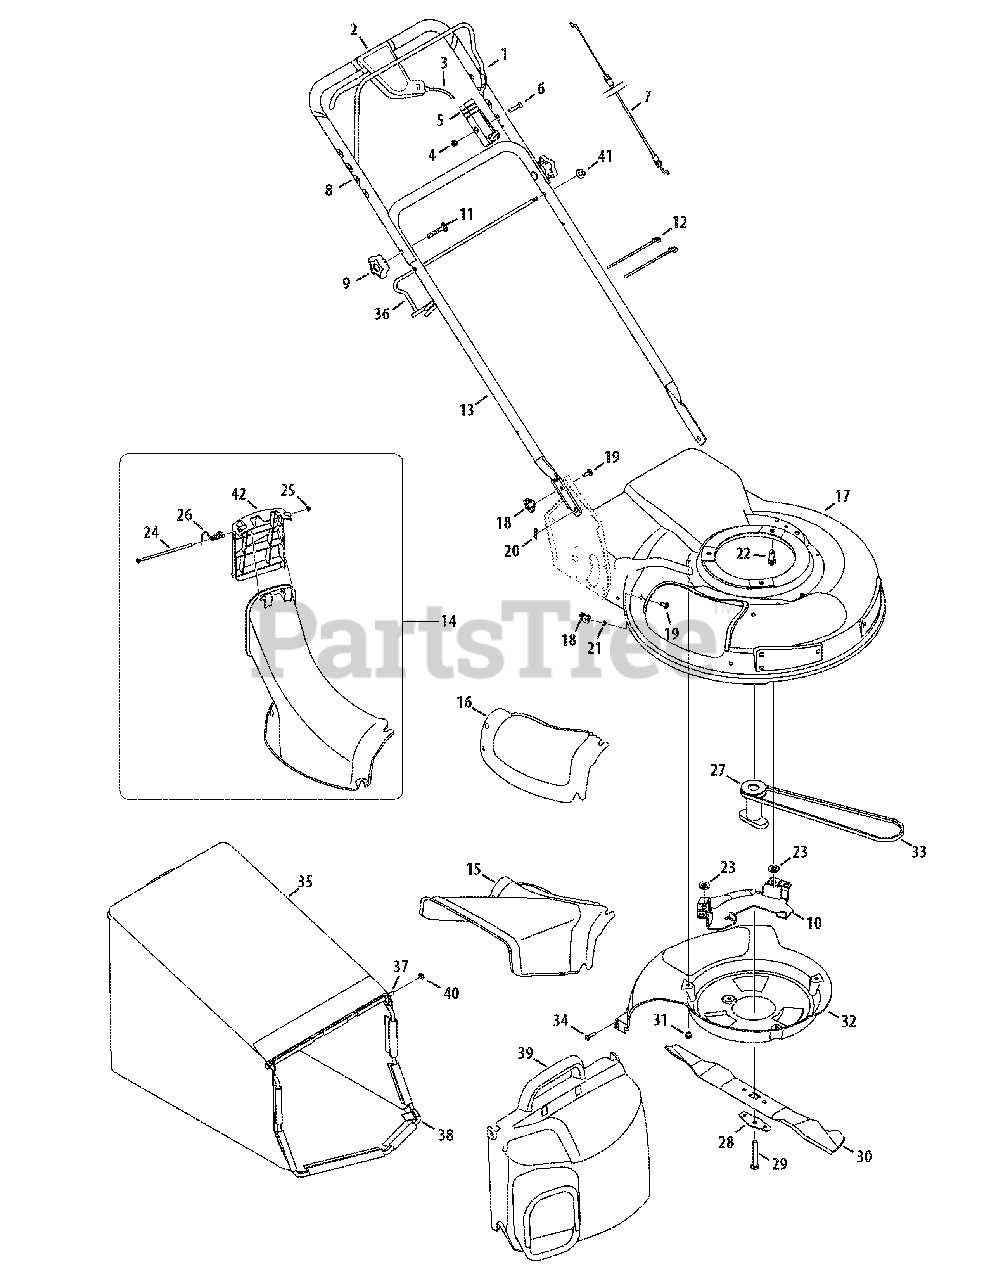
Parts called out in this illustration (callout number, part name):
1	Control Lever
2	Control Lever Assembly
3	Drive Cable
4	Top Lock Nut 1/4-20
5	Control Housing
6	Oval C-Sunk Screw
7	Control Cable
8	Upper Handle
9	Star Knob
10	Belt Keeper
11	Carriage Bolt 5/16-18 x 2.0
12	Cable Tie
14	Chute Assembly
15	Side-Discharge Chute
16	Mulch Cover
17	Deck 21-inch
18	Wing Nut
19	Carriage Bolt 1/4-20 x .75"
20	Cotter Pin
21	Push Nut .25 x ID x .50 OD
22	Sems Screw 3/8-16 x 1.00
23	Washer, Flat, .407 x .812 x .135
24	Pivot Rod
25	Push Cap
26	Torsion Spring
27	Blade Adapter
28	Blade Bell Support
29	Hex Bolt 3/8-24 x 2.5
30	21" Mulching Blade
31	Screw 1/4-20 x 3.75
32	Baffle
33	Belt 3/8 x 39.24
34	HL Screw 1/4-15 x .75
35	Grass Catcher
36	Support Rod w/ Rope Guide
37	Pivot Rod
38	Grass Bag Frame
39	Grass Bag Cover
40	Cap Nut
41	Hex Nut 5/16-18
42	Chute Door
